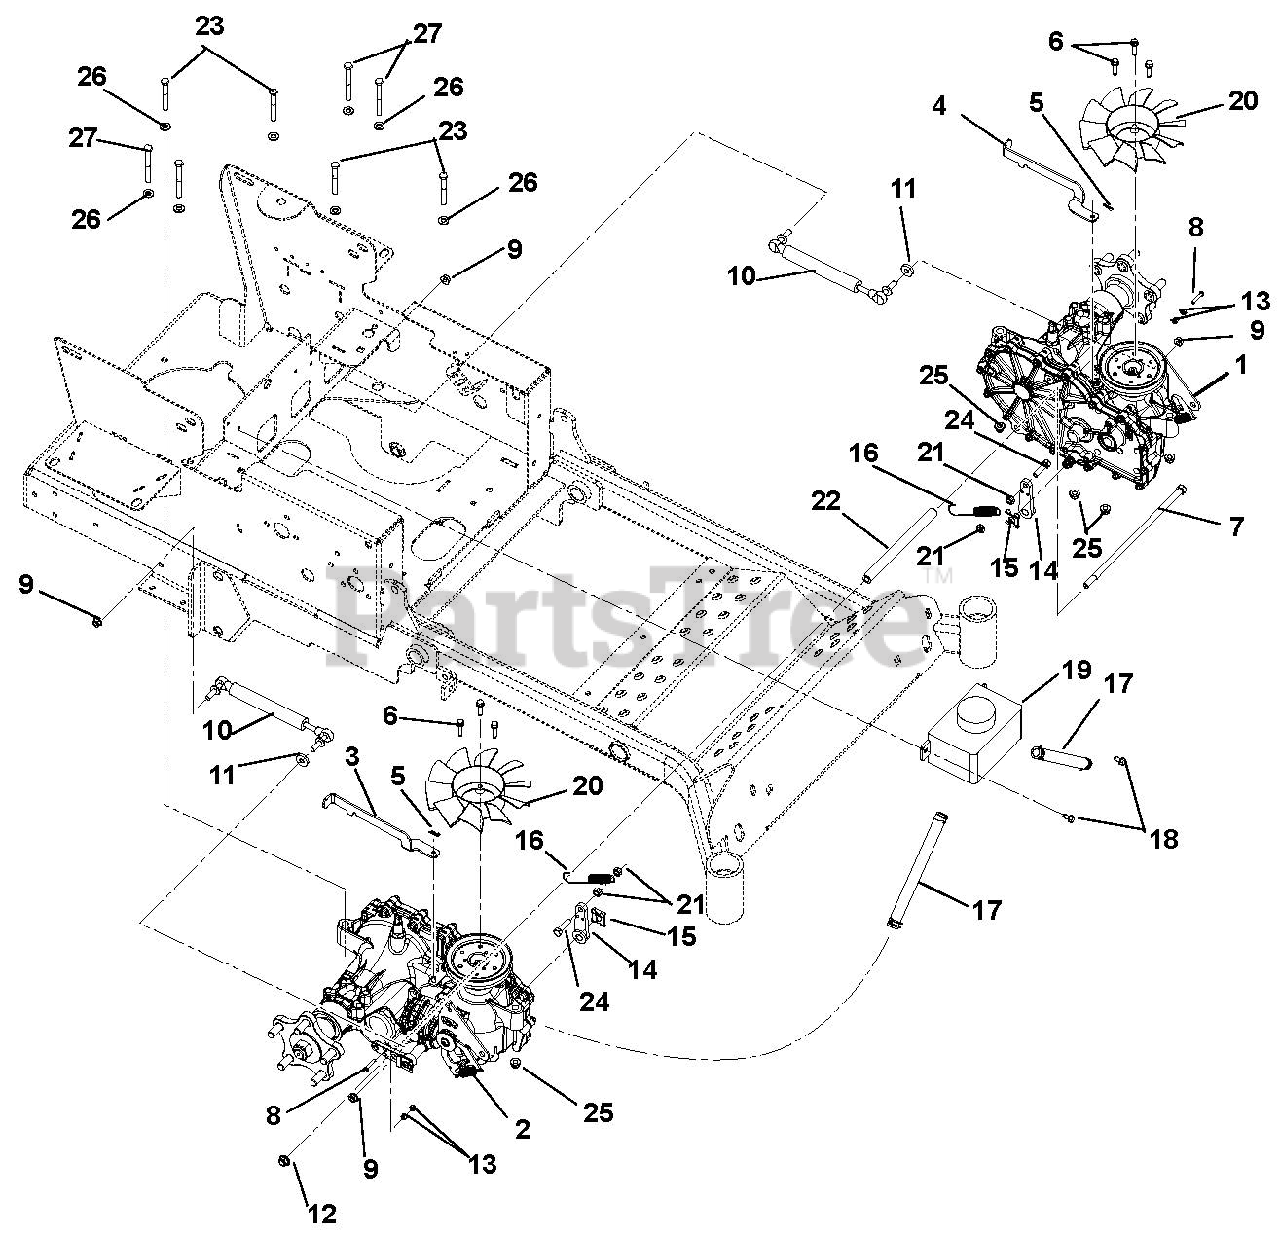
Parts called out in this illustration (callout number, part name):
1	Transaxle, 2800 Series- Left Hand
2	Transaxle, 2800 Series- Right Hand
3	Right Hand Dump Valve Lever- Black
4	Left Hand Dump Valve Lever- Black
5	Pin-Hair-Internal .06 x .18 x .77
6	Screw, Tapping .25-20 x 1.00 Hex Washer Head Thread
7	Bolt, Hex .38-16 x 11.00 Grade 5
8	Screw, Machine 8-32 x 1.00 Hex Washer Head
9	Nut, M8-1.25 WHIZ Lock
11	Washer, Flat-Steel .38 x .87 x .179
12	Nut, .38-16 Nyloc Flange
13	Nut, Locking-Nylon 8-32
14	Arm, Brake
15	Clip, Brake Arm
16	Spring, Tension .056 x .60 x 4.60 LG
17	Assembly, Hydro Overflow Tank Hose
18	Screw, Tapping .25-20 x .50 Hex Washer Head Thread
19	Tank, Expansion
20	Fan, Cooling
21	Nut, Locking-Center .31-18
22	Spacer, .38 ID x 5/8 OD x 7.72
23	Bolt, Hex .31-18 x 2.50 Grade 5
24	Bolt, Hex .31-18 x 1.25 Grade 5
25	Nut, Nyloc Flange .312-18
26	Washer, Flat-Steel .344 x .688 x .065
27	Bolt, Hex .31-18 x 3.00 Grade 5
